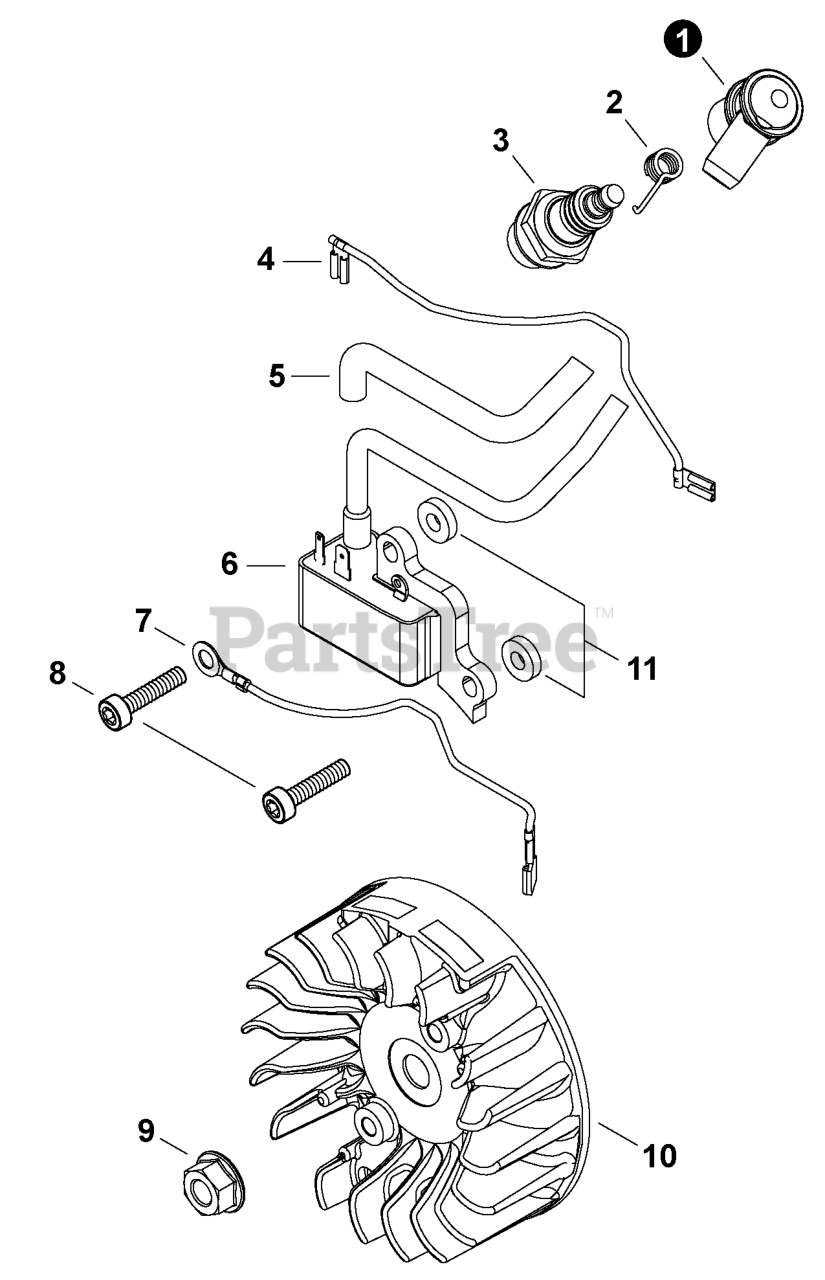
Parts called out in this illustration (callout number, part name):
1	CAP, SPARK PLUG
2	TERMINAL, SPARK PLUG
3	SPARK PLUG - BPMR8Y
4	LEAD - IGNITION
5	TUBE, INSULATOR
6	COIL, IGNITION
7	LEAD - GROUND
8	BOLT, TORX 5x20
9	NUT, FLANGE M8
10	FLYWHEEL
11	WASHER 5.2x12x3
